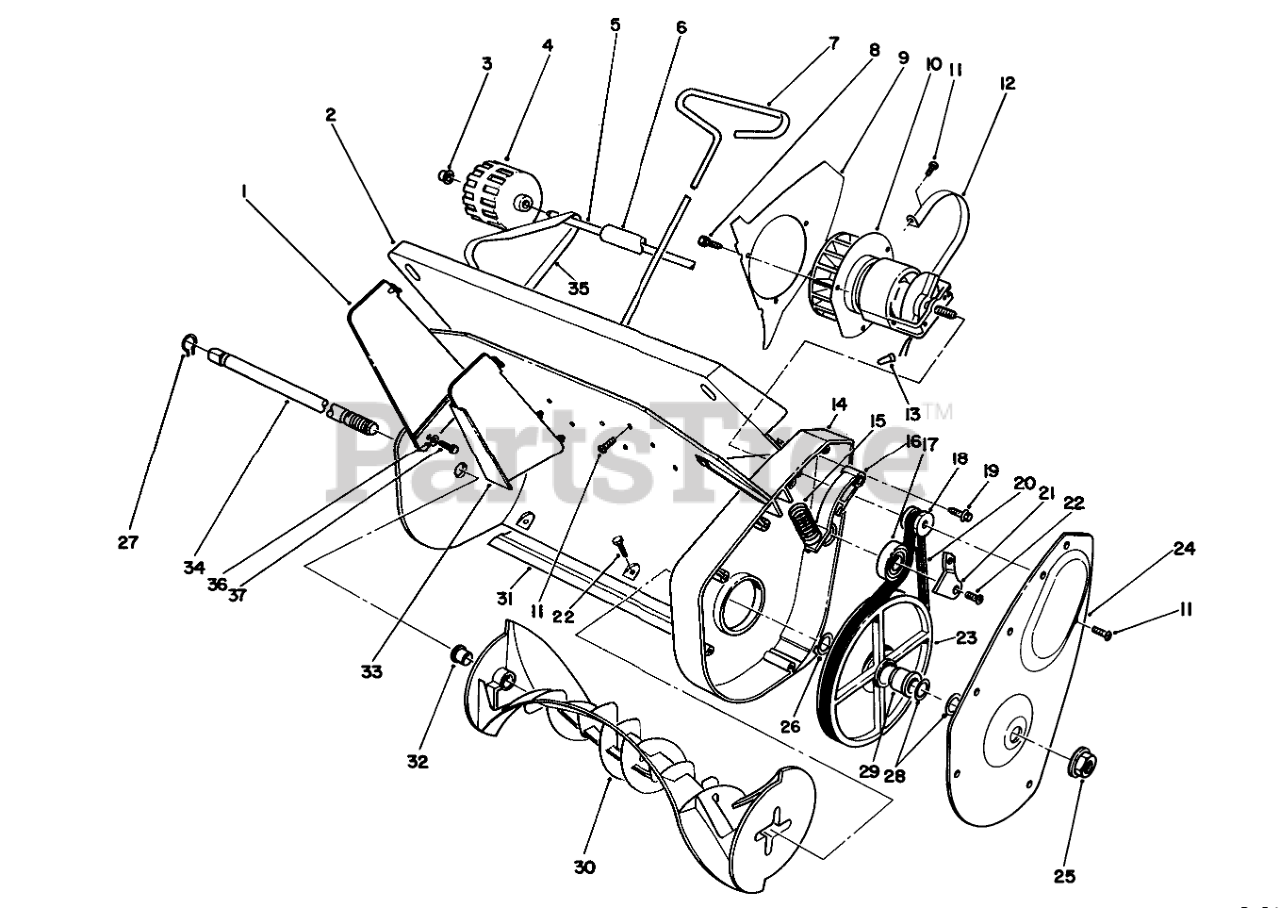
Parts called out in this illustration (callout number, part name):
1	VANE - OUTER
2	MOUNT - VANE
3	PUSHNUT-CAP, WASHER
4	Wheel
5	AXLE SHAFT
6	SLEEVE, AXLE
7	VANE ADJUSTING ROD
8	10-16 X .31 SCREW
9	AIR BAFFLE
10	MOTOR, 1200 PWR CURVE
11	Screw
12	MOTOR STRAP
13	Connector
14	HOUSING - 1200
15	SPRING
16	1200 PC - IDLER ARM
17	Bearing-Ball
18	DRIVE PULLEY
19	SCREW-HWHTF
20	BELT - DRIVE
21	1200 PC-IDLER PULL. RET
22	#8 X .625" PHILPS PAN H
23	PULLEY - DRIVEN
24	Belt Case Cover
25	NUT-HF
26	WASHER-THRUST
27	RING-RETAINING
28	THRUST WASHER (THICK)
29	DRIVEN PULLEY BUSHING
30	ROTOR, 1200
31	1200 SCRAPER, 12"
32	BUSHING-ROTOR
33	VANE - CENTER
34	ROTOR SHAFT, 1200
35	BRACKET-WHEEL,RH
36	WASHER-FLAT
37	SCREW-PPH
